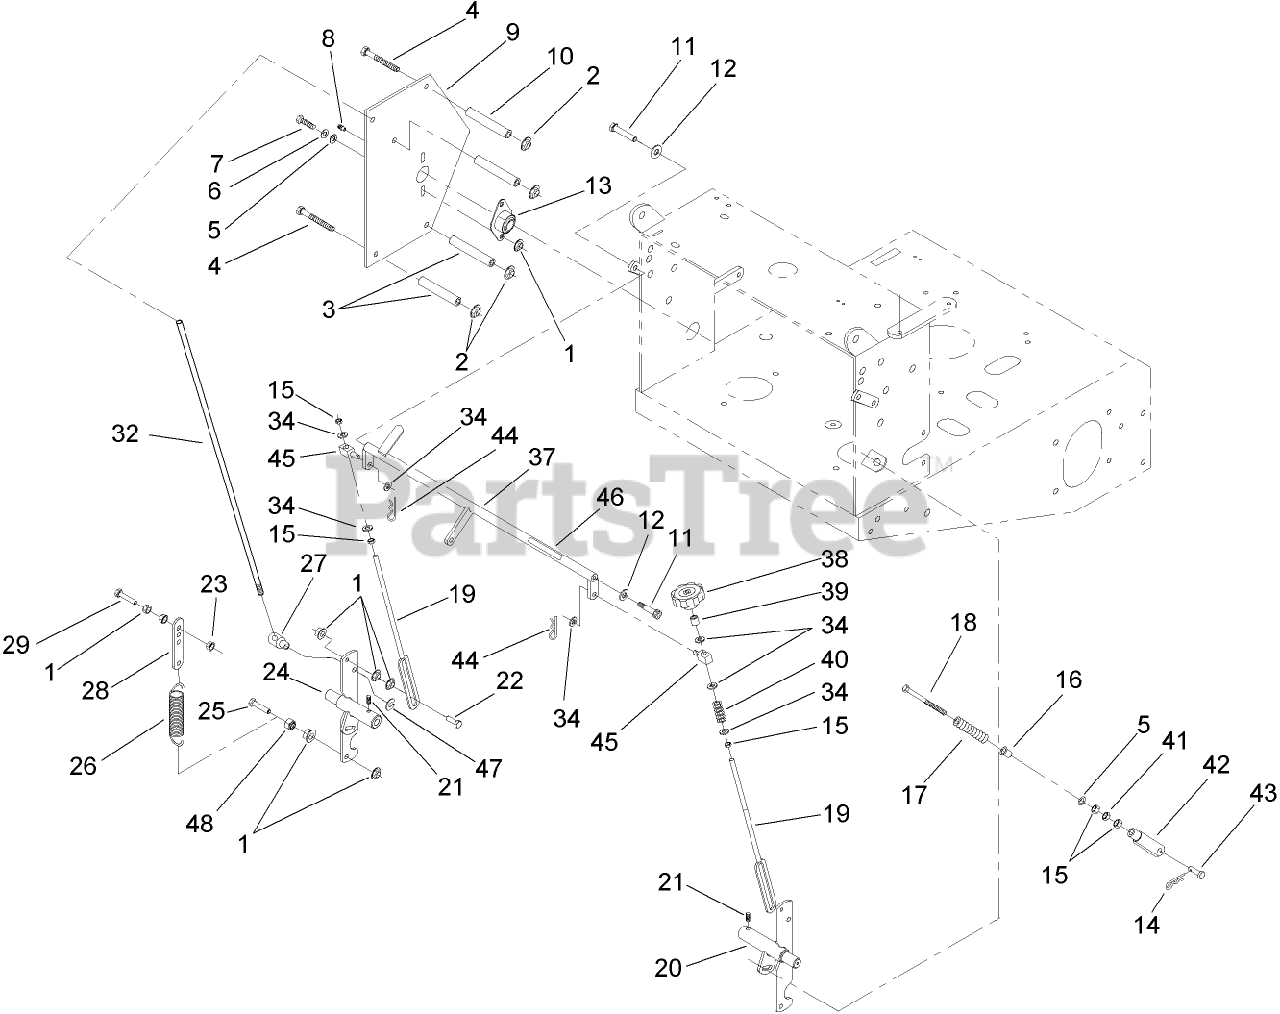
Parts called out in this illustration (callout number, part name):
1	NUT-HF
2	NUT-HHF, WHIZ
3	SPACER-SHIELD
4	SCREW-HH
5	WASHER-FLAT
6	WASHER-LOCK
7	SCREW-HH
8	FITTING-GREASE
9	SHIELD-CONTROL
10	Spacer-Shield
11	SCREW-HSH
12	WASHER-FLAT
13	BEARING-FLANGE, SIDE
14	PIN-COTTER
15	NUT-HEX
16	BUSHING-NYLON, FLANGED
17	SPRING-RETURN, NEUTRAL
18	BOLT-RETURN, NEUTRAL
19	LINK-CONTROL, SPEED
20	SHAFT-CONTROL, RH
21	SCREW-SET
22	SCREW-HH
23	NUT-LOCK, NI
24	Shaft-Control, LH
25	SCREW-HH
26	SPRING-EXTENSION
27	SWIVEL-LEVER, DRIVE
28	TAB-SPRING, EXTENSION
29	BOLT-TAP, HH
32	ROD-LEVER, DRIVE
34	WASHER-PLAIN
37	Crank-Control, Speed
38	KNOB-TRACKING
39	SPACER
40	SPRING-COMPRESSION
41	NUT-JAM
42	YOKE-ADJUSTABLE
43	PIN-CLEVIS
44	PIN-COTTER
45	SWIVEL-ADJUSTABLE, SHORT
46	DECAL-TRACKING
47	RING-RETAINING
48	NUT-JAM
